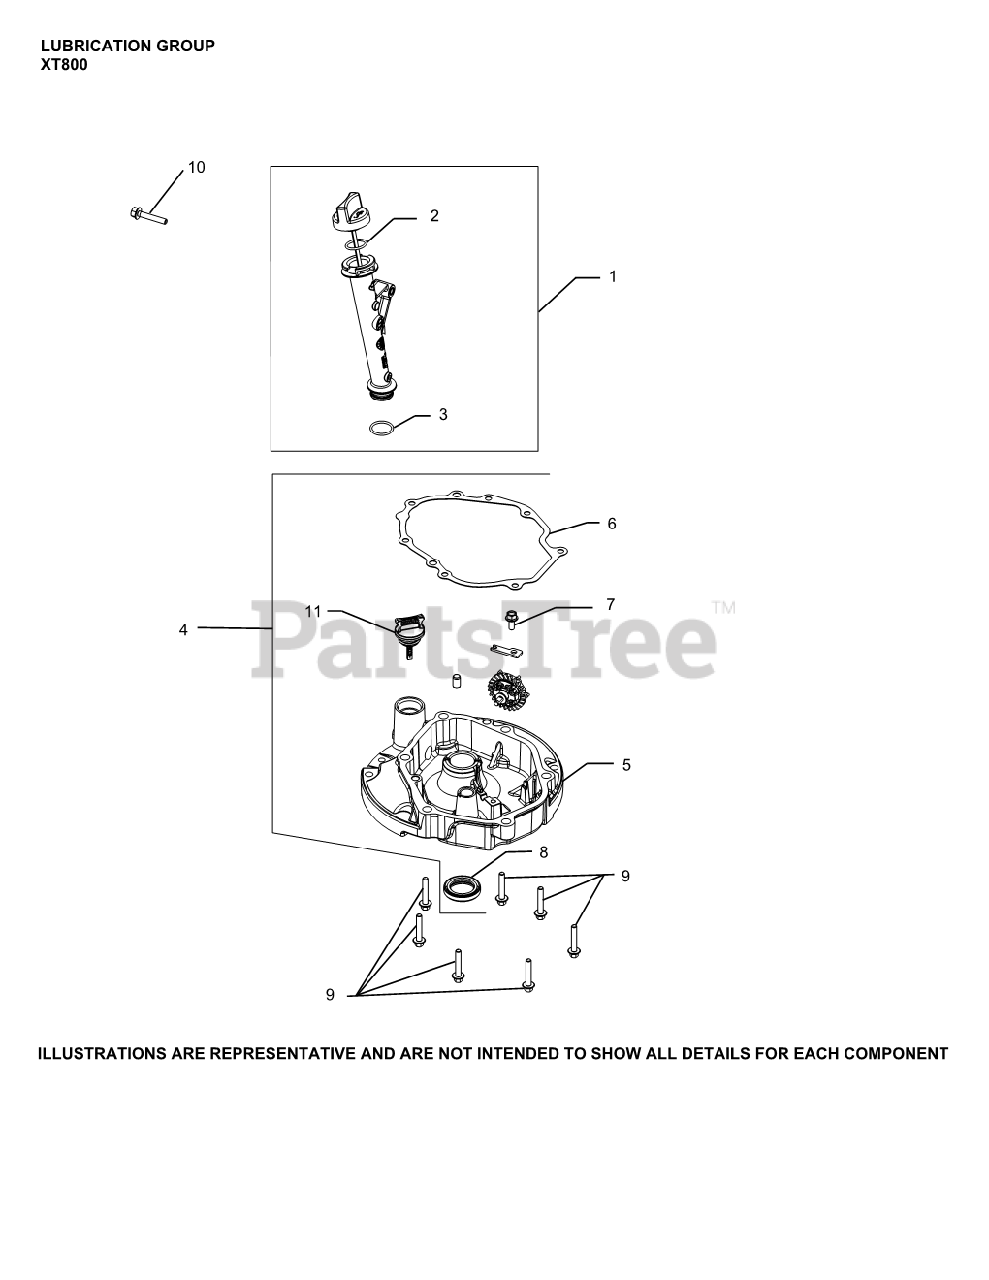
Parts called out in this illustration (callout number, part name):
1	"PUSH-IN" DIPSTICK AND TUBE ASSEMBLY USE 14 123 20-S
2	O-RING (CAP)
3	O-RING, OIL FILL TUBE
5	KIT, OIL PAN
7	SCREW, HEX FLANGE (M6)-USE 25 086 433-S
9	SCREW, HEX FLANGE (M8) USE 25 086 456-S
10	SCREW, HEX FLANGE (M6) - USE 25 086 435-S
